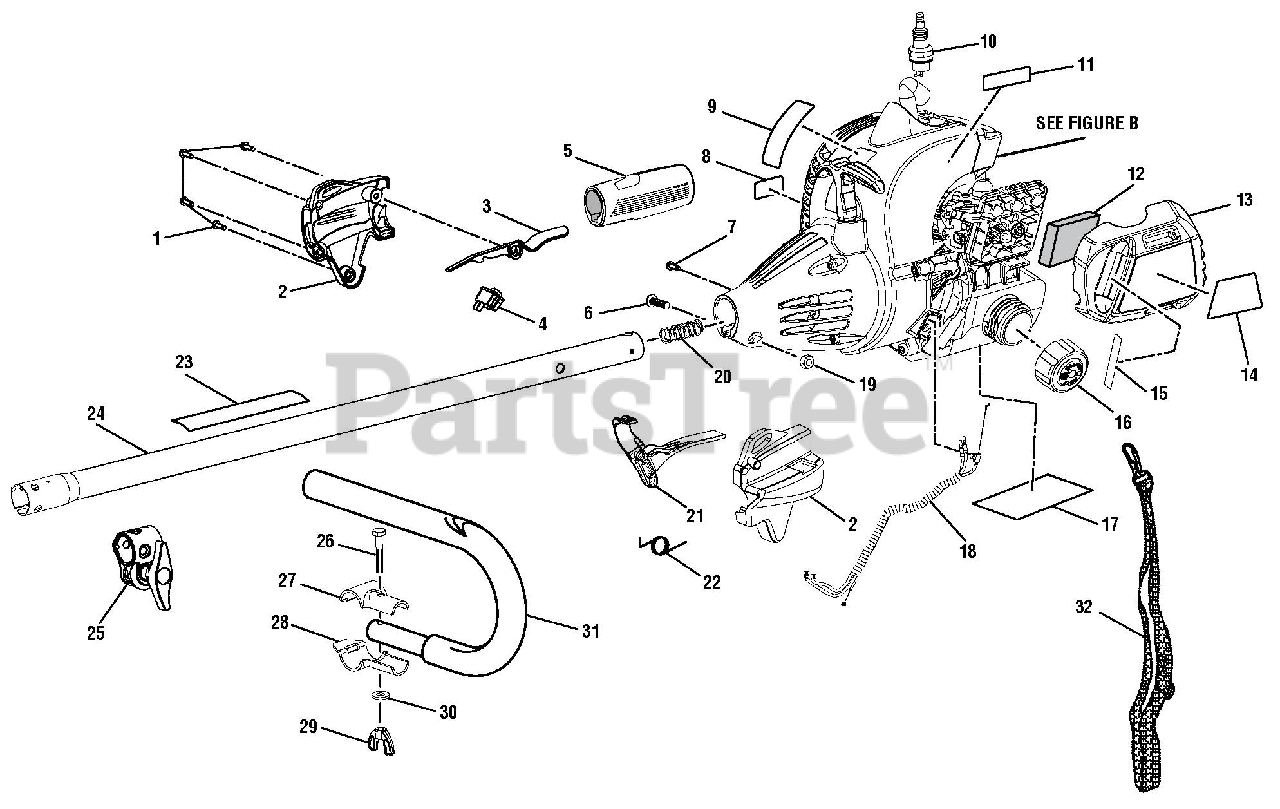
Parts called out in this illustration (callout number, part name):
1	Screw (M4 x 20 mm)
2	Control Handle Assembly
3	Trigger Lock
4	Switch (Momentary Contact)
5	Rear Handle
6	Bolt (M6 x 20 mm)
7	Screw (M4 x 8 mm., Torx T.F.)
8	Combustion Warning Label
9	Logo Label
10	Spark Plug (Champion RCJ6Y)
11	Primer Label
12	Air Filter
13	Air Box Cover
14	Starting Label
15	Run Start Label
16	Fuel Cap Assembly (1.5 in. Diameter)
17	Fuel Tank Warning Label
18	Throttle and Lead Assembly
19	Hex Nut (M6)
20	Compression Spring
21	Throttle Trigger
22	Throttle Spring
23	Warning Decal
24	Upper Boom Assembly
25	Boom Clamp Assembly
26	Bolt (1/4-20 x 1-1/2 in., Hex Hd.)
27	Top "J" Handle Clamp
28	Bottom "J" Handle Clamp
29	Wing Nut (1/4-20)
31	"J" Handle and Grip
32	Shoulder Harness
